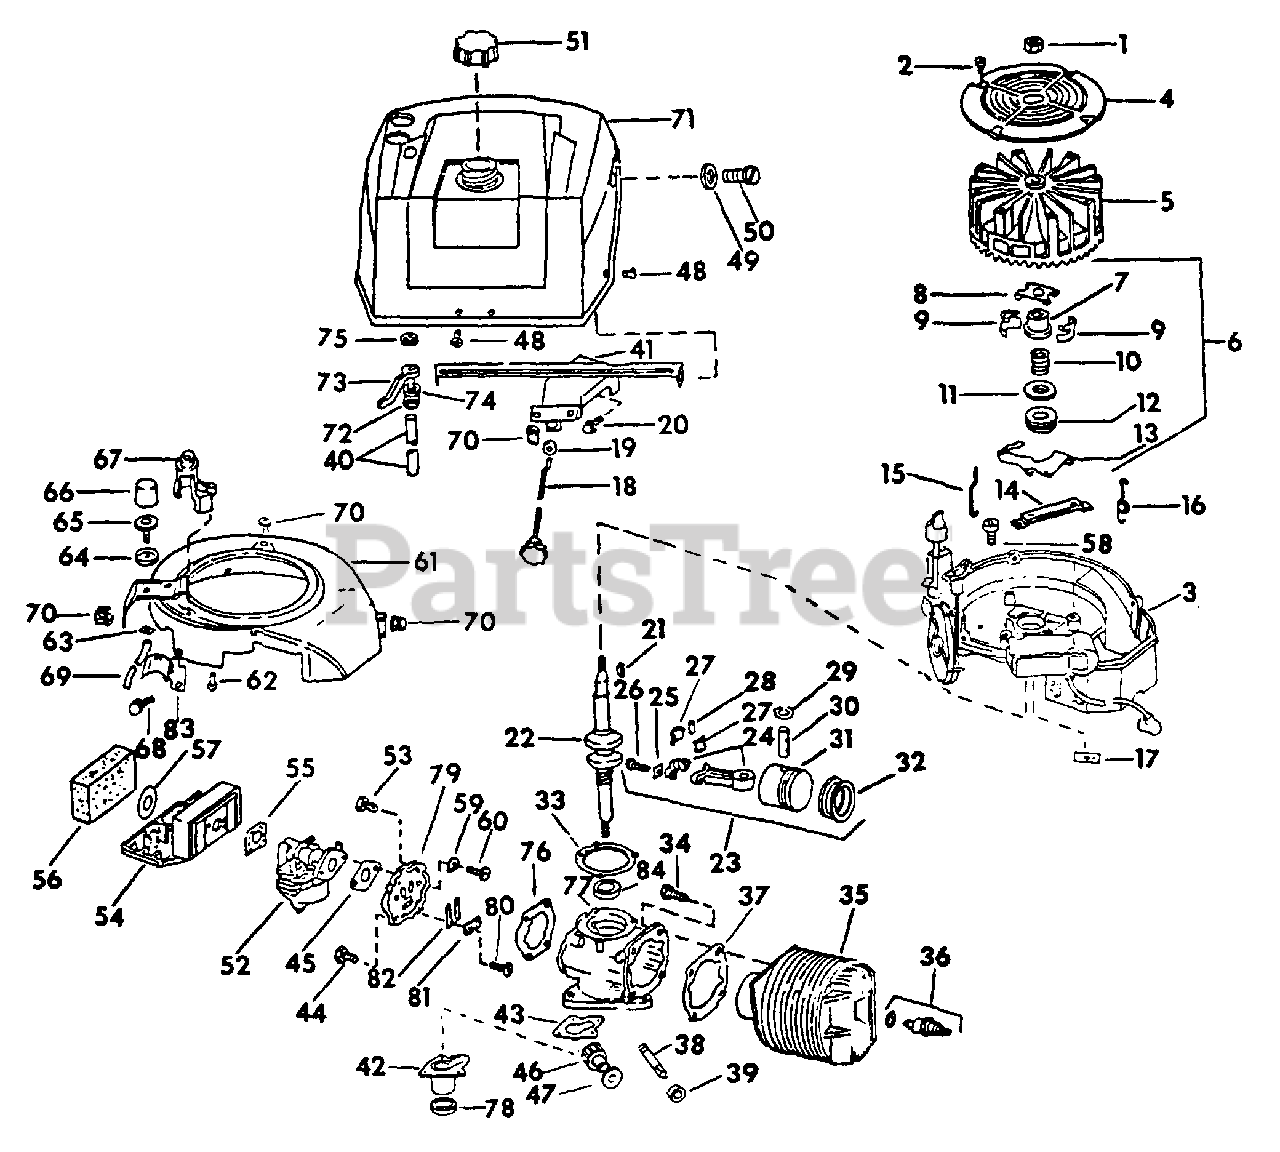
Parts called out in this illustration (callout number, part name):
1	NUT 7/16-20 HEX.
2	SCREW 10-24 1/2 TRUSS-HD REC TAP
3	MAGNETO ASSY
4	SCREEN, FLYWHEEL
6	GOVERNOR ASSY
7	COLLAR, GOVERNOR
8	YOKE, GOVERNOR
9	WEIGHT, GOVERNOR
10	SPRING, GOVERNOR
11	WASHER, THRUST
12	COLLAR, THRUST
13	LEVER, GOVERNOR
14	BRACKET, GOVERNOR LEVER
15	ROD, GOVERNOR
16	SPRING, VARIABLE SPEED
21	KEY, CRANKSHAFT
23	PISTON & CONNECTING ROD ASSY
24	ROD ASSY, CONNECTING
25	LOCKPLATE, SCREW
26	SCREW, CONNECTING ROD
27	LINER, CONNECTING ROD
28	BEARING SET, NEEDLE
29	RING, RETAINING
32	RING SET, PISTON -2 RINGS
33	GASKET, CRANKCASE TO ARM PLATE .010
34	SCREW, CYL TO CRANKCASE
36	SPARK PLUG & GASKET
37	GASKET, CYL TO CRANKCASE
39	SEAL, DRIVE OIL
41	BRACKET, SHROUD
43	GASKET, CRANKSHAFT
44	SCREW, HH REED PLATE TO CRANKCASE
45	GASKET, CARBURETOR
46	GEAR, DRIVESHAFT
47	WASHER, THRUST BRG
48	SCREW, COVER MTG
52	CARBURETOR ASSY
53	SCREW. HH REED PLATE TO CRANKCASE
54	CASE, AIR FILTER
56	ELEMENT, FILTER
58	SCREW, 5/16-18 X 1-1/4 HEX-HD CAP
61	BAFFLE, BRACKET
66	BULB, PRIMER
67	BRACKET & EYELET
70	GROMMET, COVER MTG
71	SHROUD, TANK & VALVE ASSY
72	CLIP, SPRING
76	GASKET, REED PLATE
77	CRANKCASE AND SEAL ASSY
79	REED PLATE ASSY
81	PLATE, BACKUP
83	GUARD, ROPE
